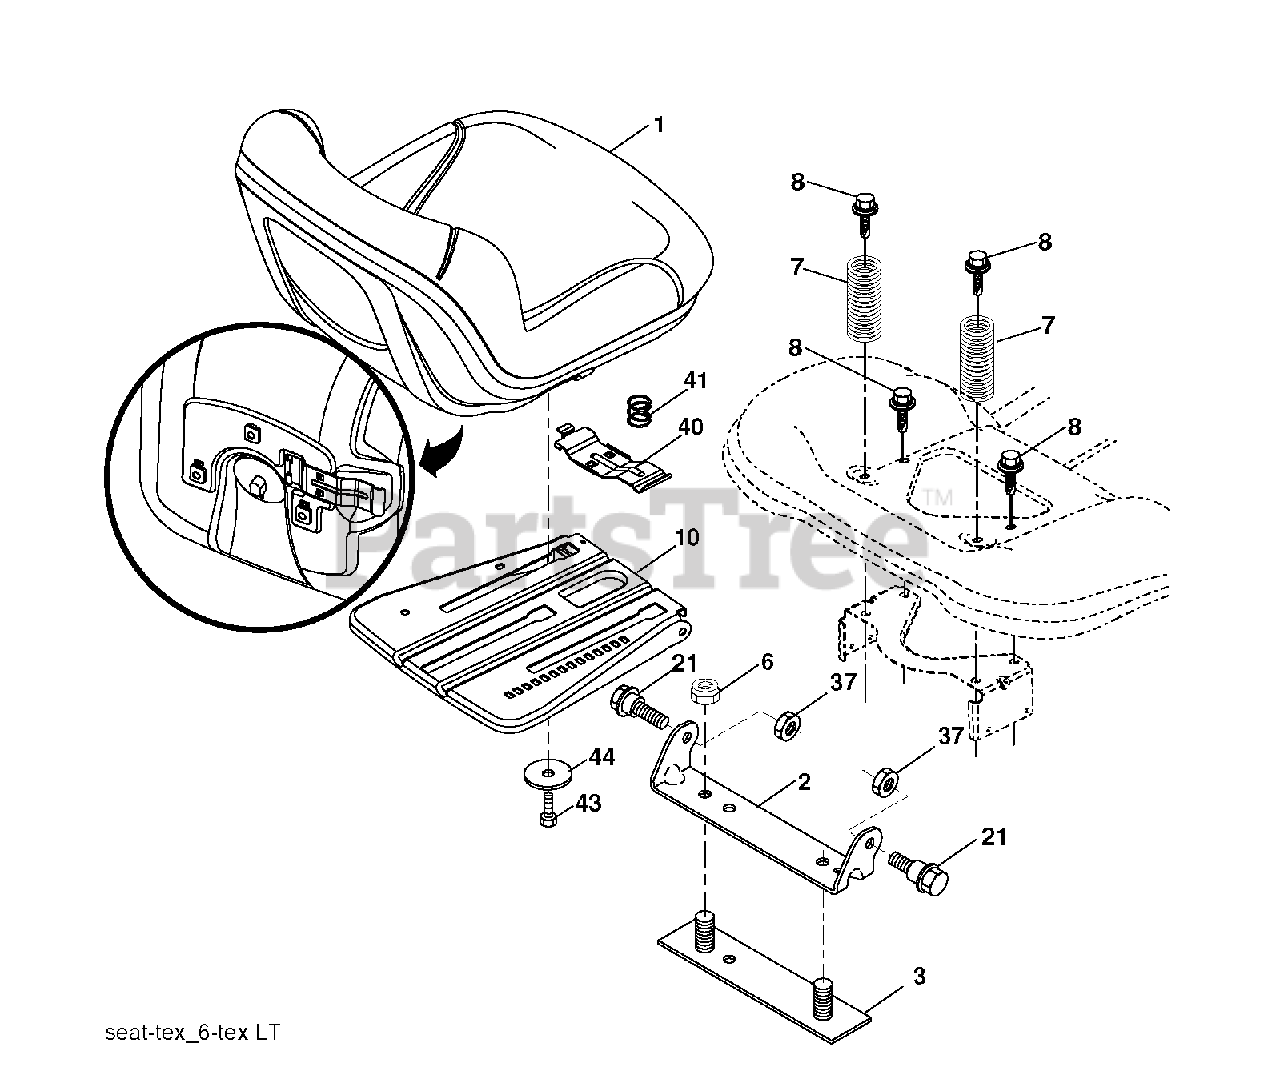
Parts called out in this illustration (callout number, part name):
1	SEAT.TG130.BLACK.NO/LOGO.
2	BRKT.PIVOT.FENDER
6	NUT
7	SPRING COMPRESSION
8	BOLT, 5/16-18 X 1 3/4
10	PAN.ASM.SEAT.3PT
21	BOLT.SHOULDER.5/16-18
37	NUT.71038.31-18.HEX.NYLOCK
40	HANDLE.SLIDE.SEAT.TEX.BLACK
41	SPRING.LATCH.SEAT.TEX
44	WASHER 13/32 X 2-3/8 X 12GA
